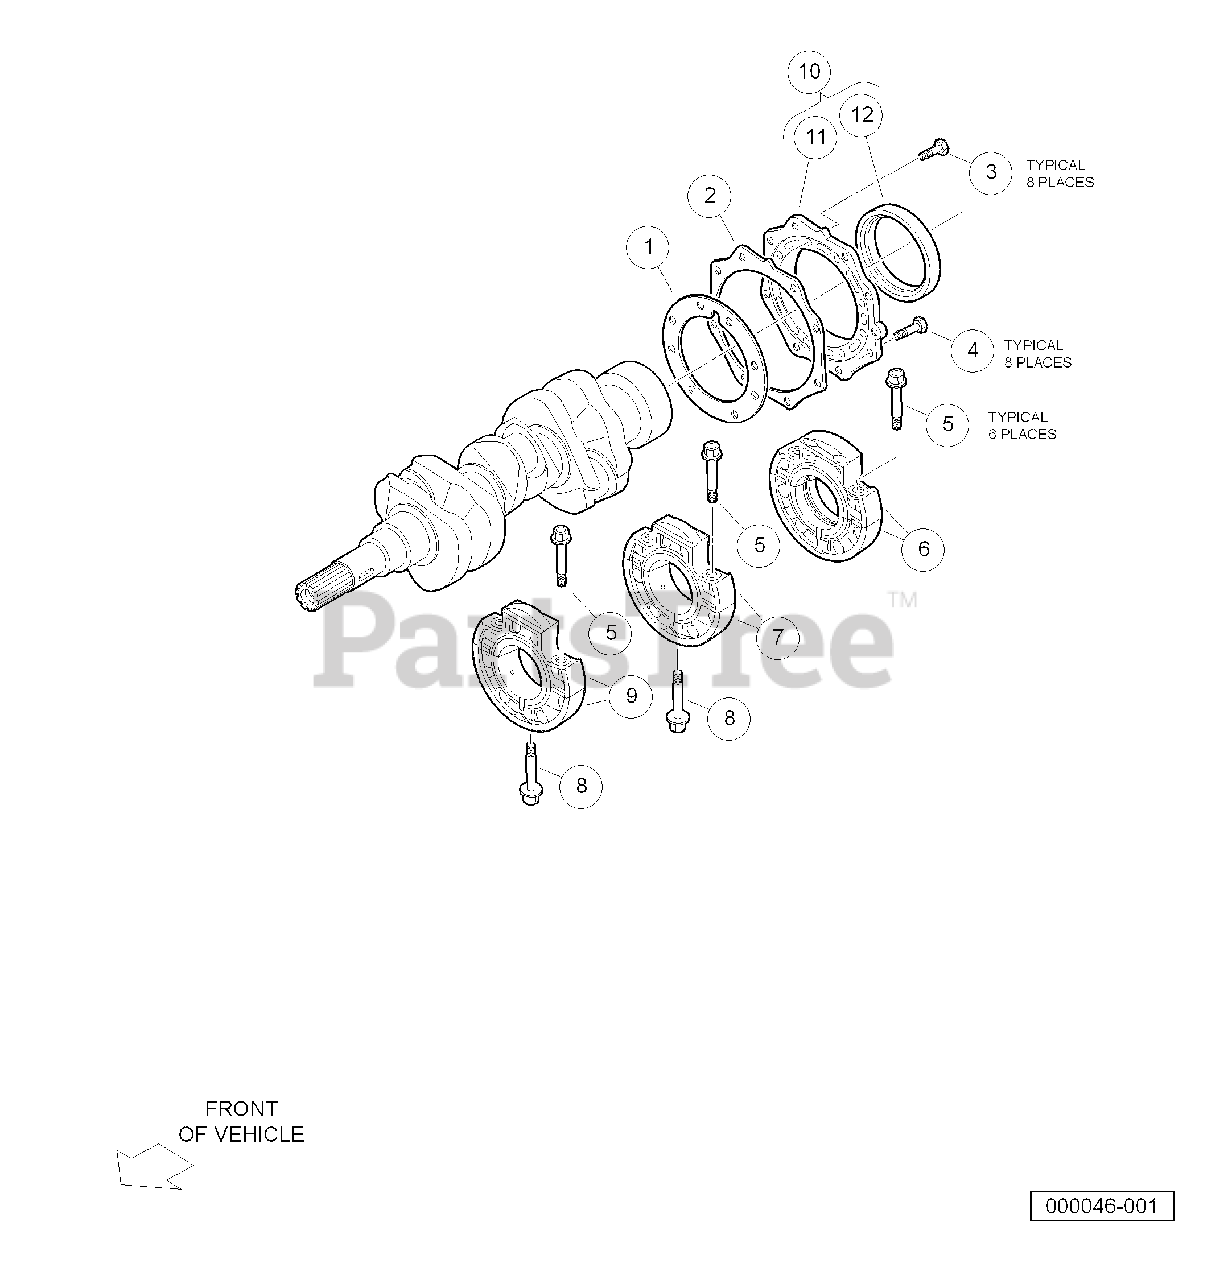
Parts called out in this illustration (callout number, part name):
1	Gasket, Bearing Case
2	Gasket, Cover
3	Bolt, M6 X 1 X 20
4	Bolt, M6 X 1 X 22
5	Bolt, Bearing Case, Top
6	Assy Case, Main Brg, First
7	Assy Case, Main Brg, Sec
8	Bolt, Bearing Case, Bottom
9	Assy Case, Main Brg, Third
10	Assy, Cover, Bearing Case
11	Cover, Bearing Case
